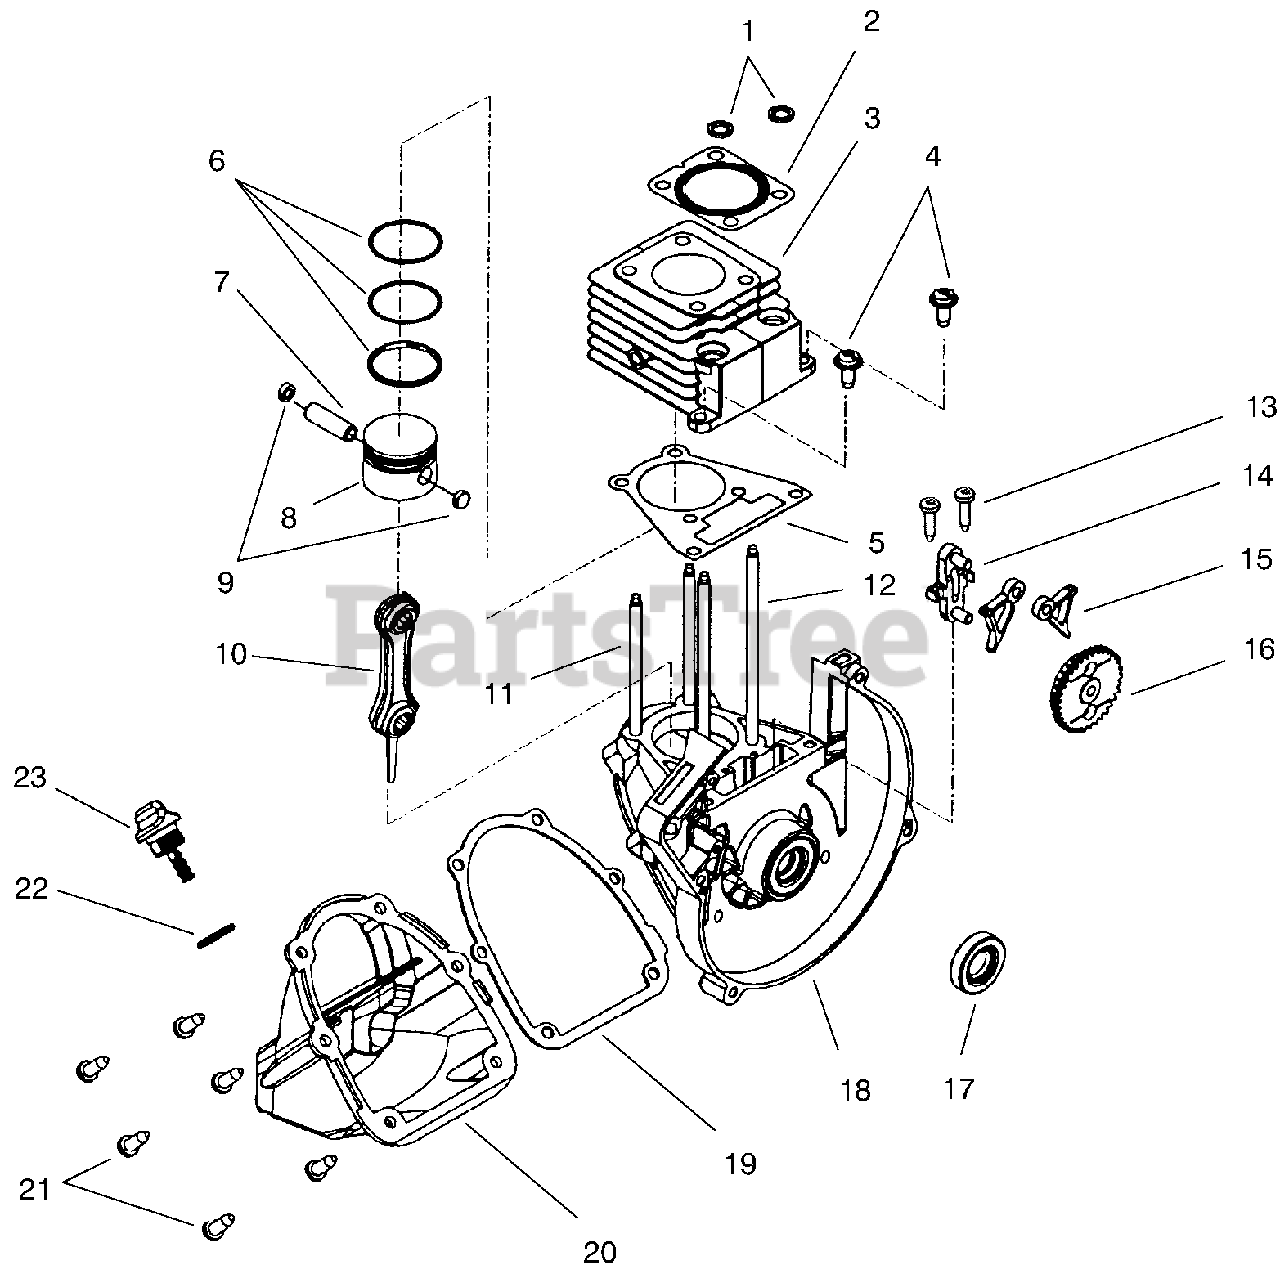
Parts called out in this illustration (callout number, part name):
1	O Ring-Push Rod Tube
2	Gasket-Cylinder Head
3	Cylinder
5	Gasket-Cylinder
6	Piston Ring Set
7	Pin-Wrist
9	Button-Wrist Pin
10	Rod-Connecting
11	Cylinder Stud (83.5mm)
12	Cylinder Stud (115.5mm)
13	Screw-Cam Bracket
14	Bracket-Cam
15	Follower-Cam
16	Cam Gear
18	Crankcase W/Power Shaft (Incl. Ref. #11, 12, & 17)
19	Gasket-Oil Pan
20	Pan-Oil
23	Plug-Oil Fill (Incl. Ref. #22)
